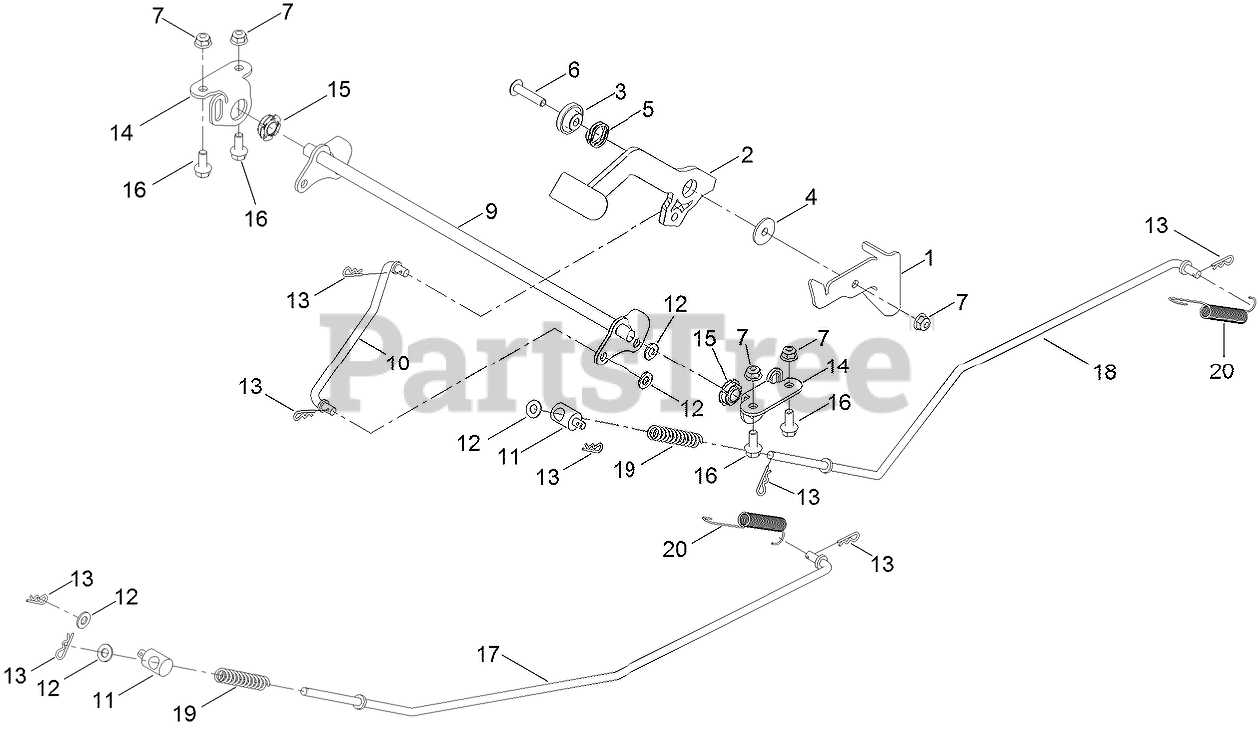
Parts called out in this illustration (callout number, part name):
1	DETENT-BRAKE
2	LEVER-BRAKE
3	BUSHING-FLANGE
4	BUSHING-BRAKE, FLANGED
5	WASHER-WAVE
6	SCREW-TORX
7	NUT-HF
9	BELLCRANK-BRAKE
10	ROD-BRAKE, INTERMEDIATE
11	FITTING-ROD
12	WASHER-PLAIN
13	PIN-HAIR
14	PLATE-SUPPORT, BELLCRANK
15	BEARING-SPHERICAL
16	SCREW-HHF
17	ROD-BRAKE, RH
18	ROD-BRAKE, LH
19	SPRING-COMPRESSION
20	SPRING-EXTENSION
